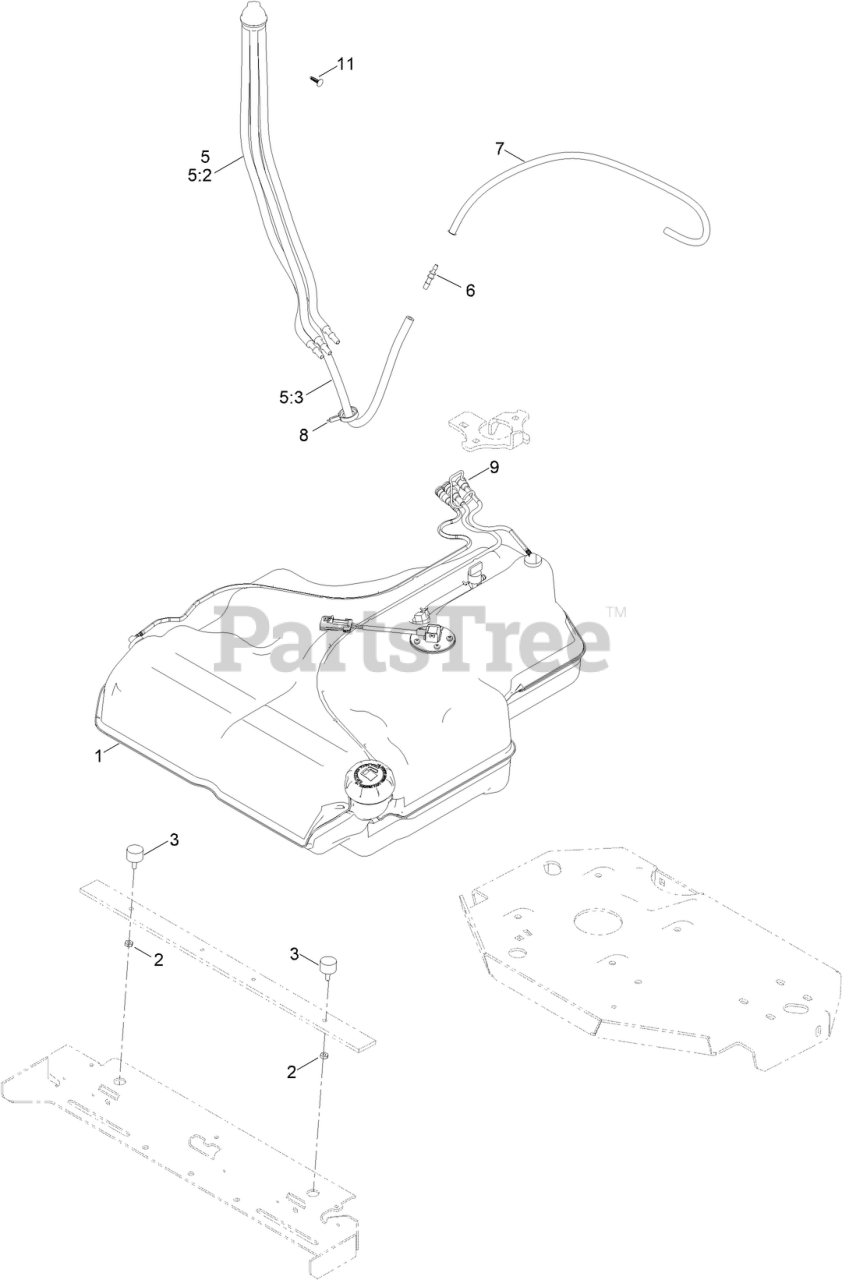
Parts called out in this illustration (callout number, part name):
1	FUEL TANK ASM
2	NUT-JAM
3	BUMPER
5	FUEL MANIFOLD VENT ASM
5:2	HOSE-FUEL
5:3	HOSE-FUEL
6	BARB-FUEL
7	HOSE-FUEL
8	CLAMP-HOSE
9	RETAINER-LINE, VAPOR
11	PLUG-PLASTIC
